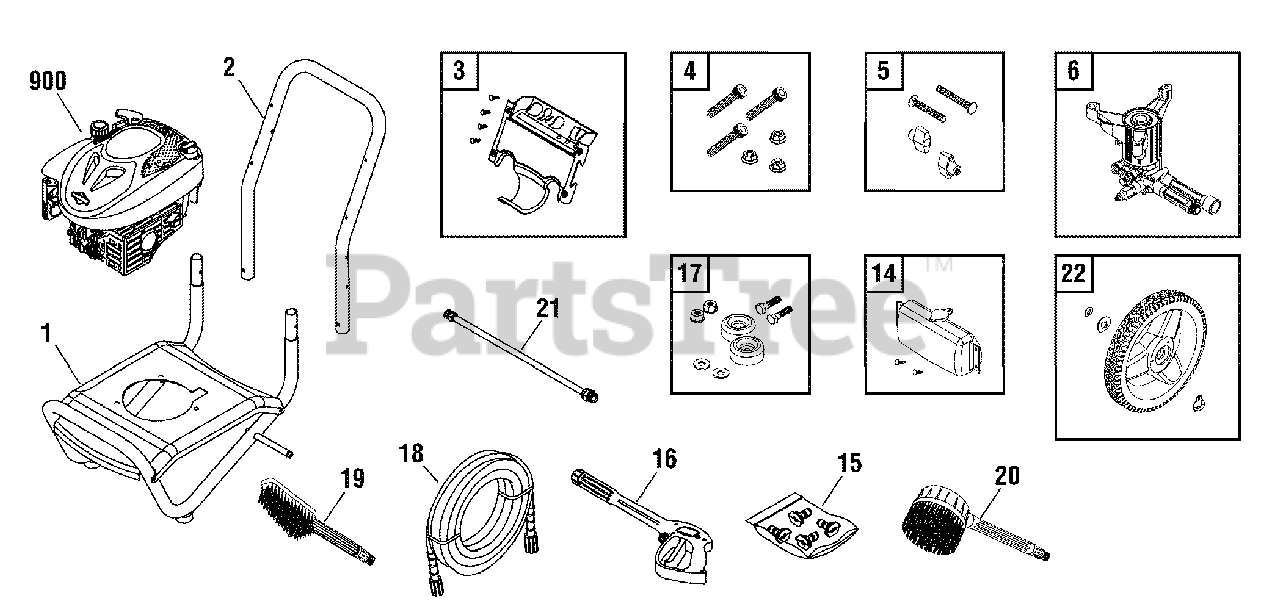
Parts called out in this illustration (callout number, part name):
2	HANDLE
4	KIT, Hardware, Pump Mounting
5	KIT, Hardware, Handle
6	PUMP
15	KIT, QC Nozzles
16	GUN
17	KIT, Vibration Mount
18	HOSE, 25’
20	BRUSH, Rotating
21	EXTENSION, QC
900	* ENGINE
